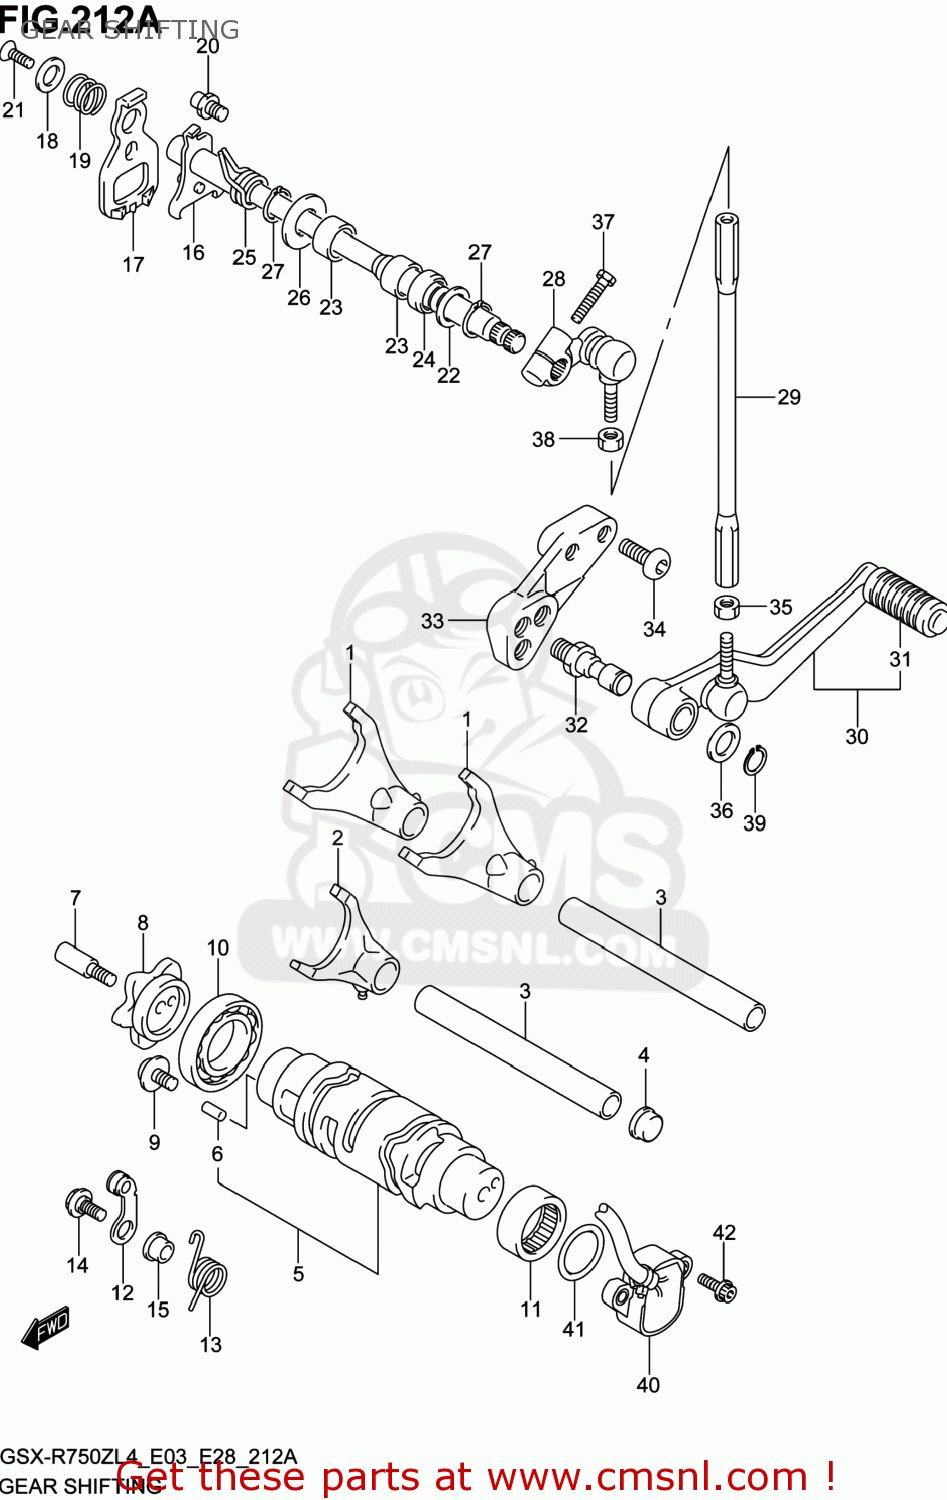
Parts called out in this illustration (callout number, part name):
1	FORK,GEAR SHIFT NO.1
2	FORK,GEAR SHIFT NO.3
3	SHAFT,GEAR SHIFT FORK NO.1
4	PLUG,GEAR SHIFT FORK SHAFT
5	CAM,GEAR SHIFT
6	PIN
7	BOLT,GEAR SHIFT CAM PLATE
8	PLATE,GEAR SHIFT CAM
9	SCREW(6X12)
10	BEARING(25X47X8)
11	BEARING(25X32X12)
12	STOPPER,SHIFT CAM
13	SPRING,GEAR SHIFT CAM STOPPER
14	BOLT,SHIFT CAM STOPPER ARM
15	SPACER,CAM STOPPER
16	SHAFT,GEAR SHIFT
17	PLATE,GEAR SHIFT CAM DRIVE
18	WASHER,GEAR SHIFT SHAFT END
19	SPRING,GEAR SHIFT PLATE RETURN
20	STOPPER,GEAR SHIFT ARM
21	SCREW(6X16)
22	WASHER(14X29X0.8)
23	BEARING(14X20X12)
24	SEAL,OIL(14X22X7.3)
25	SPRING
26	SHIM(14X24X1)
27	CIRCLIP
28	ARM,GEAR SHIFT LINK
29	ROD,GEAR SHIFT LINK
30	LEVER ASSY,GEAR SHIFT
31	RUBBER,GEAR SHIFT PEDAL
32	SHAFT,GEAR SHIFT LEVER
33	BRACKET,GEAR SHIFT LEVER
34	BOLT(8X20)
35	NUT
36	WASHER(12.5X20X1)
37	BOLT
38	NUT
39	CIRCLIP
40	SENSOR ASSY,GEAR POSITION
41	O RING(D:2.4,ID:26.2)
42	BOLT(5X16)
